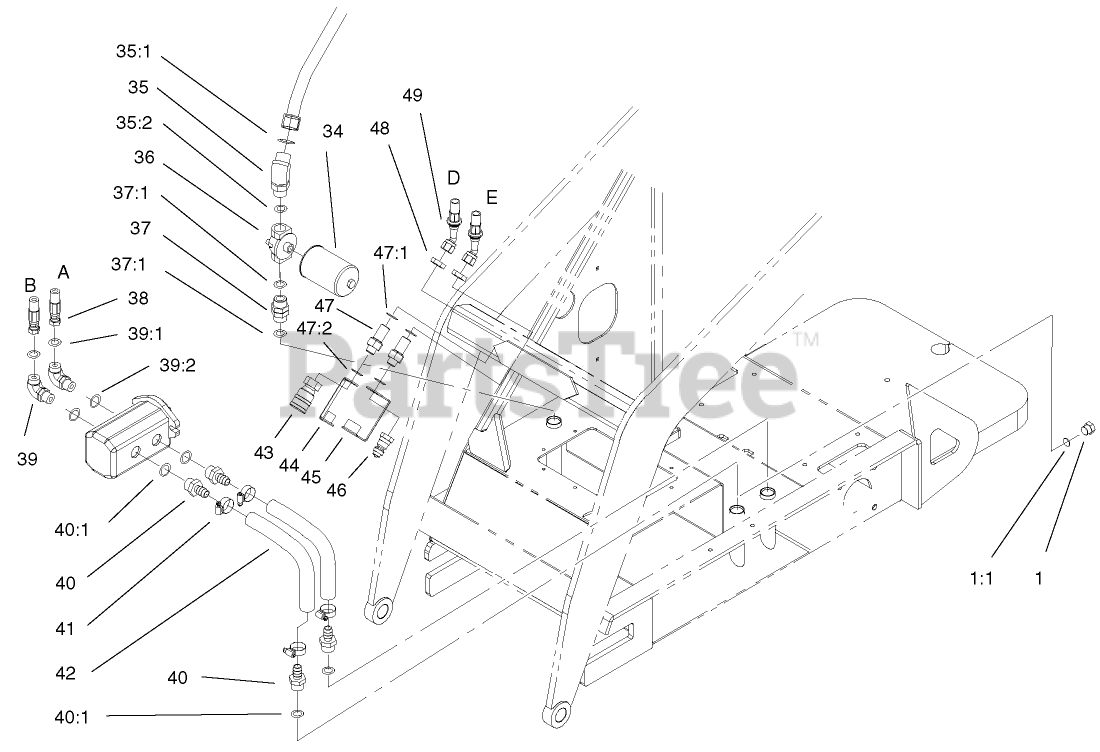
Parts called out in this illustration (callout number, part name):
1	PLUG-HEX
1:1	O-RING
34	FILTER-OIL, TRANSMISSION
35	FITTING-HYD
35:1	O-RING
35:2	O-RING
36	HEAD-FILTER
37	FITTING-THREAD, STRAIGHT
37:1	O-RING
38	HOSE-HYD
39	FITTING-ELBOW 90
39:1	O-RING
39:2	O-RING
40	FITTING-STRAIGHT
40:1	O-RING
41	CLAMP-HOSE
42	HOSE-SUCTION, HYD
43	FEMALE-DISCONNECT, QUICK
44	Dust Plug
45	Cap-Dust
46	MALE-DISCONNECT, QUICK
47	UNION-BULKHEAD
47:1	O-RING
47:2	O-RING
48	NUT-BULKHEAD
49	HOSE-AUX, HYD
